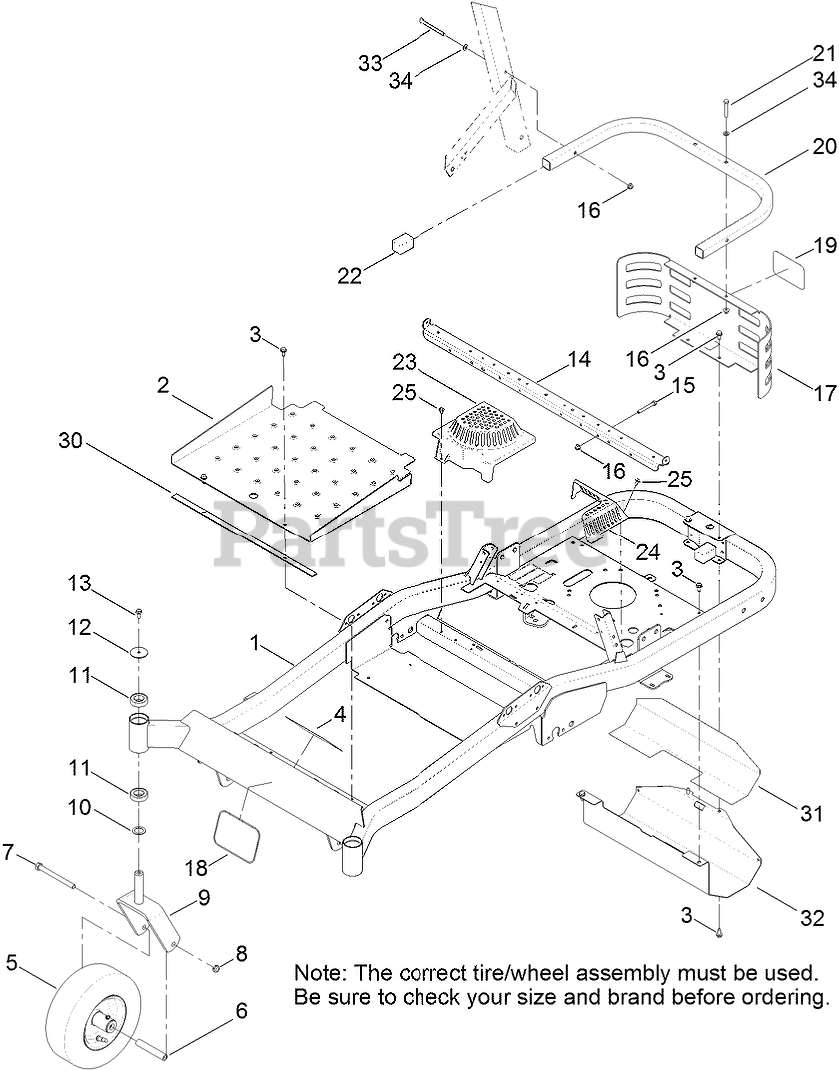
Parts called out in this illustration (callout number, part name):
2	PAN-FLOOR
3	SCREW-HWHTF
4	DECAL-SAFETY
5	TIRE AND WHEEL ASM (C S T)
5	TIRE and WHEEL ASM (Kenda)
6	BUSHING-SPANNER
7	SCREW-HH
8	NUT-LOCK, NI
9	CASTER FORK ASM
10	WASHER-THRUST
11	BEARING-BALL
12	WASHER
13	SCREW-HHF
14	SUPPORT-SEAT
15	SCREW-HH
16	NUT-HF, NI
17	GUARD-REAR
18	DECAL
20	TUBE-GUARD
21	SCREW-HH
23	COVER-FAN, RH
24	COVER-FAN, LH
25	SCREW-HHFTF
30	STRIP-VIBRATION, ANTI
31	FOIL-HEAT SHIELD
32	GUARD-MUFFLER
33	SCREW-HH
34	WASHER-PLAIN
